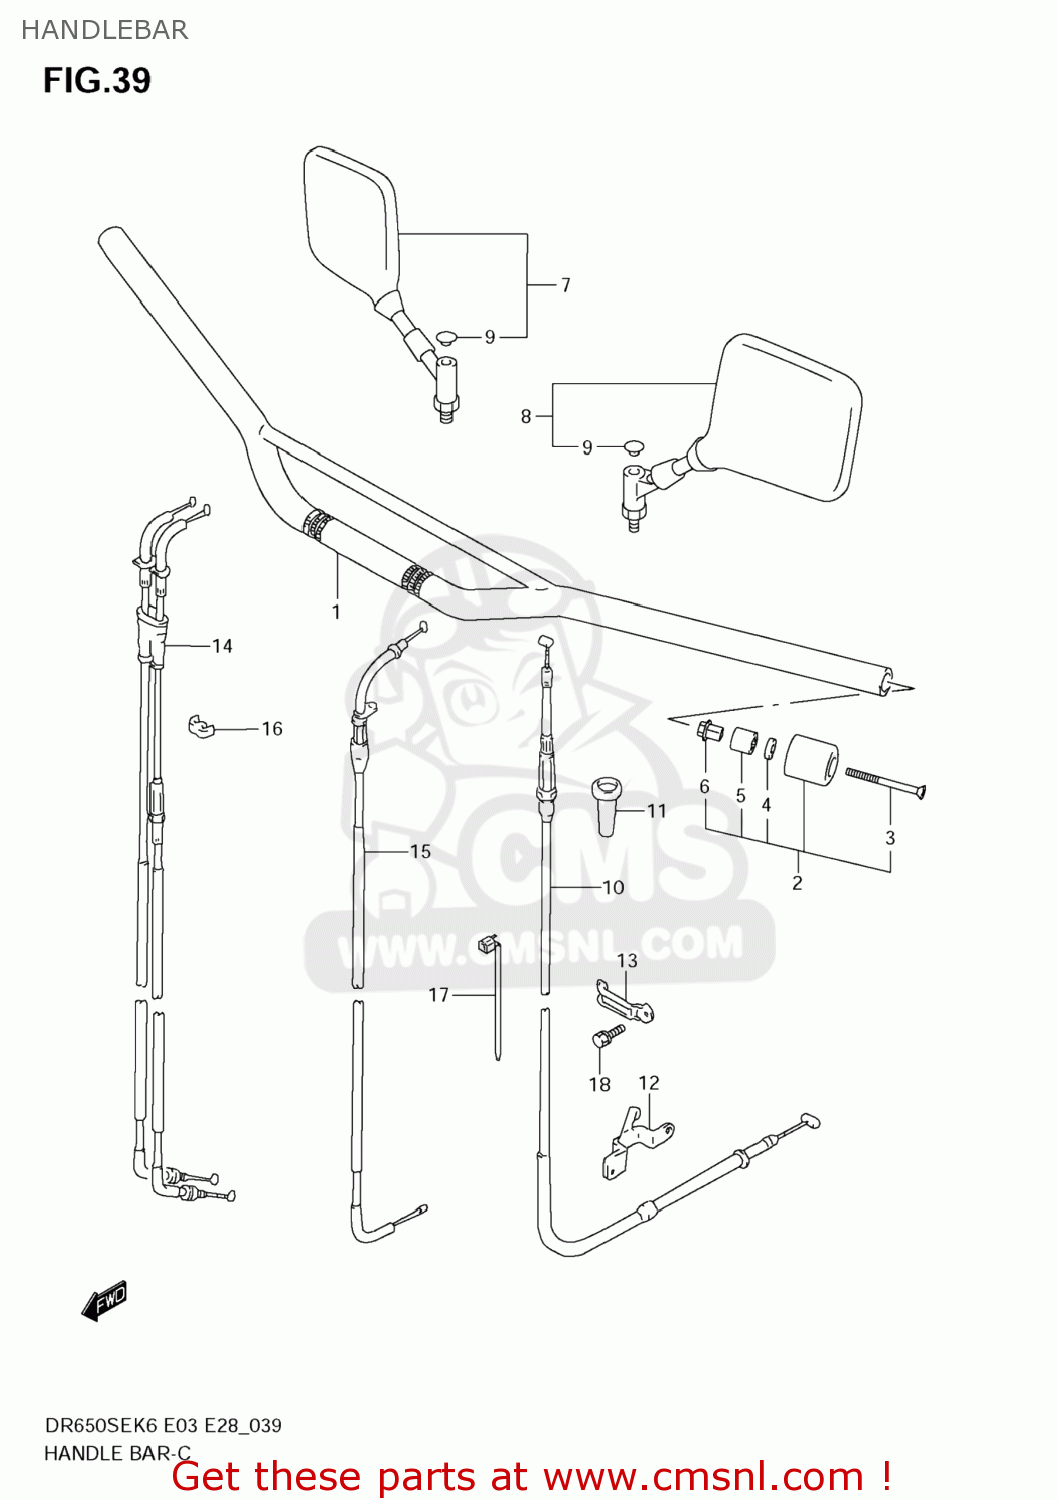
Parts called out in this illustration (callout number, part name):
1	HANDLEBAR(BLACK)
2	BALANCER,HANDL
3	SCREW
4	WASHER(6.5X16X4)
5	EXPANDER,HANDLE BALANCER
6	NUT,HANDLE BALANCER
7	MIRROR ASSY,RR VIEW,R
8	MIRROR ASSY,RR VIEW,L
9	CAP
10	CABLE ASSY,CLUTCH
11	BOOT,CLUTCH CABLE
12	STOPPER,CLUTCH CABLE
13	CLAMP
14	CABLE ASSY,THROTTLE
15	CABLE,STARTER
16	CLIP
17	CLAMP(L:235)
18	BOLT
